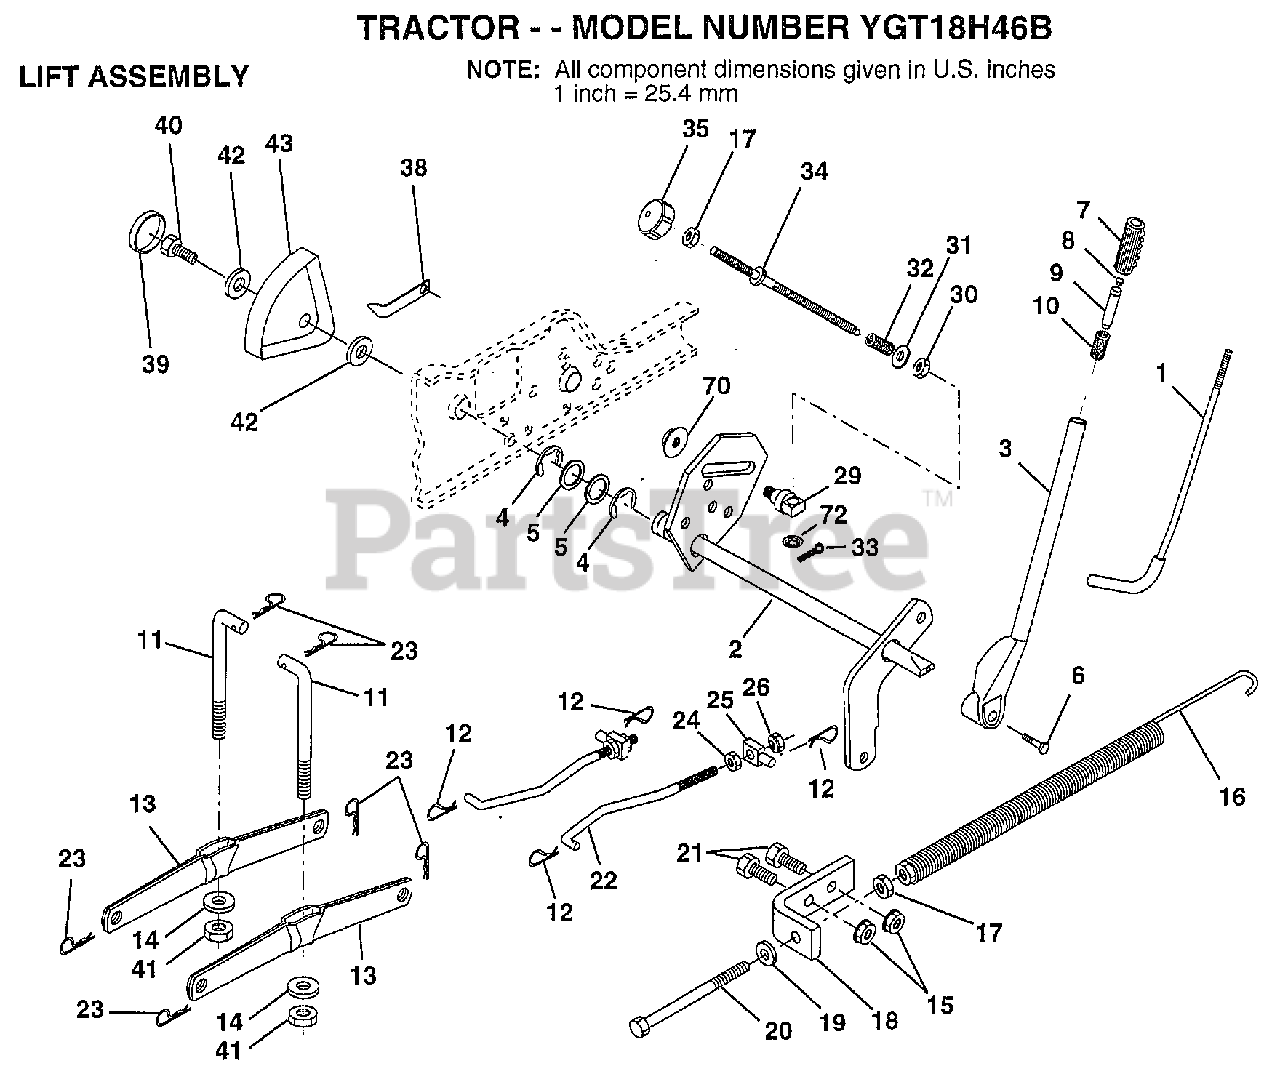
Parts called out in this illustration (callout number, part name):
1	LEVER ROD LT
2	SHAFT.ASM.LIFT.VGT
3	LEVER.ASM.LIFT.RH
4	E-RING
5	WASHER
6	"BOLT,HEX"
7	GRIP HANDLE
10	SPRING T
11	LINK.LIFT.MWR.VGT
12	RETAINER SPRING
13	ARM SUSP REAR
14	BEARING PVT LH
17	NUT
18	BRACKET SPRING AS
19	WASHER
20	BOLT-ADJ SPRING T
21	BOLT
22	LINK.FRONT
24	NUT
25	TRUNION
28	NUT LTV
29	TRUNNION
30	NUT T
31	WASHER
32	SPRING.COMP.INF.H
34	ROD.ADJ.LIFT
35	KNOB INF 3/8-16
38	POINTER-INDICAT
39	"PLUG,HOLE"
40	SCREW
41	NUT.CROWNLOCK.3/8
42	WASHER
43	HEIGHT INDICATOR
70	NUT.HXFLG.LOCK.
